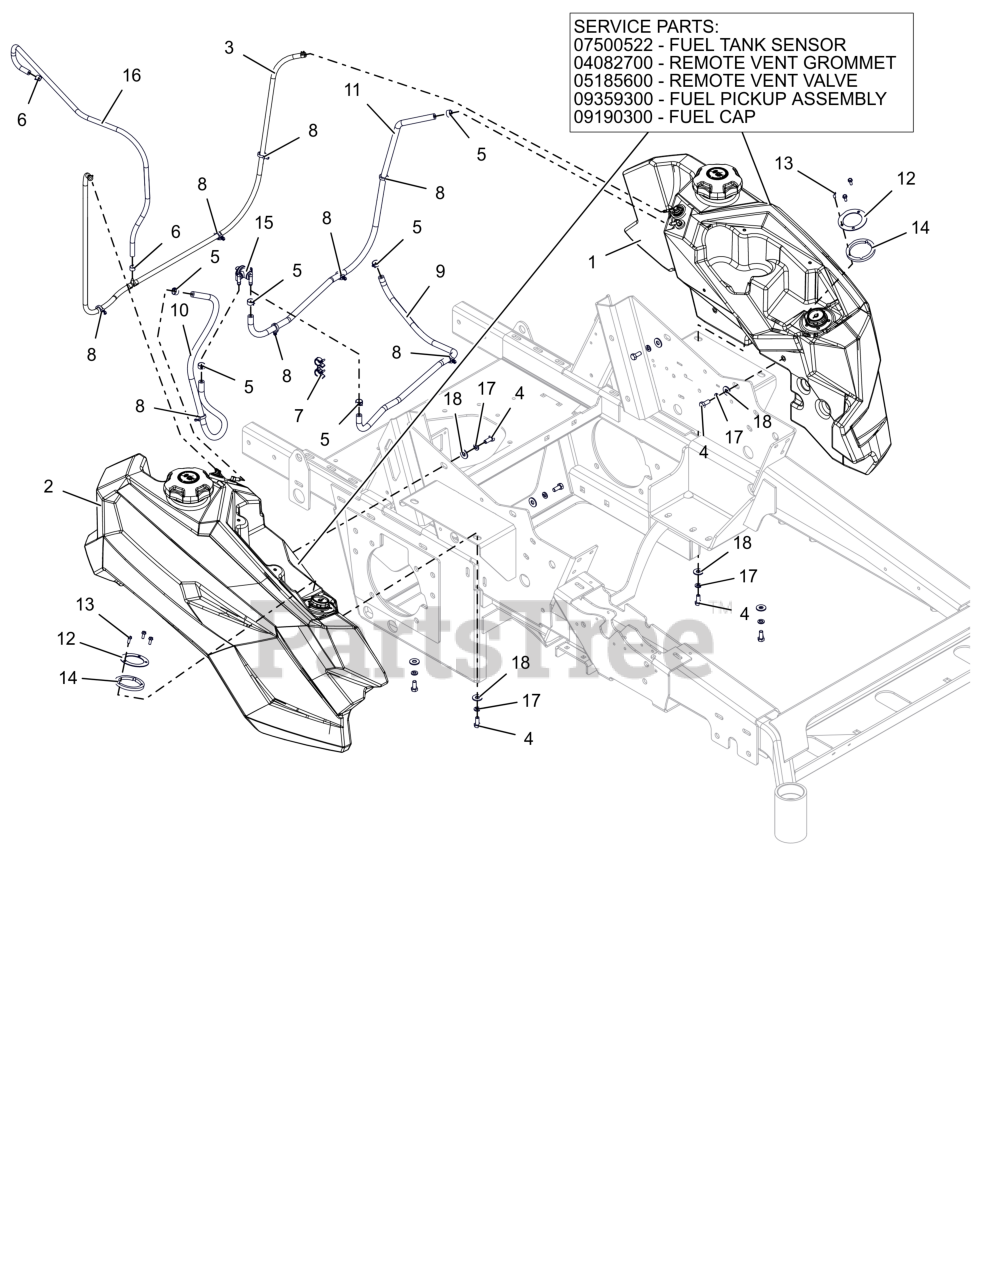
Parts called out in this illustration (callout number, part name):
1	ASM- PT300-500 LH FUEL TANK
1	GAUGE- REMOTE SEALED FUEL
1	GROMMET, REMOTE VENT NITRILE
1	VALVE, COMBINATION VENT 3/16
1	FUEL PICKUP ASSEMBLY
1	CAP, FUEL - 3.50 RATCHET INLET VENT
2	ASM- PT300-500 RH FUEL TANK
3	ASM- PT300/500/600 VENT LINE
4	BLT,HEX .31-18X.75 G5 ZCC
5	CLAMP, FUEL LINE
6	CLAMP-HOSE, SPRING .188
7	CLIP-360DEG SWIVEL.500DIA HOSE
8	CLIP- PUSH-IN X-MAS TREE CABLE
9	1 INCH OF HOSE, .25 LOW-PERM BULK GAS
10	1 INCH OF HOSE, .25 LOW-PERM BULK GAS
11	1 INCH OF HOSE, .25 LOW-PERM BULK GAS
12	RETAINER, FUEL GAUGE (BLACK)
13	SCR-MCH 10-24X.50 HWHSTAINLESS
14	SPCR, FUEL GAUGE RETAINER (BLACK)
15	VALVE, FUEL - WITH MAGNET
16	HOSE, .188 30R7 BULK
17	WSHR,LK-REG .312X.078 ZCC
18	WSHR,FLT .375X.875X.083 ZCC
